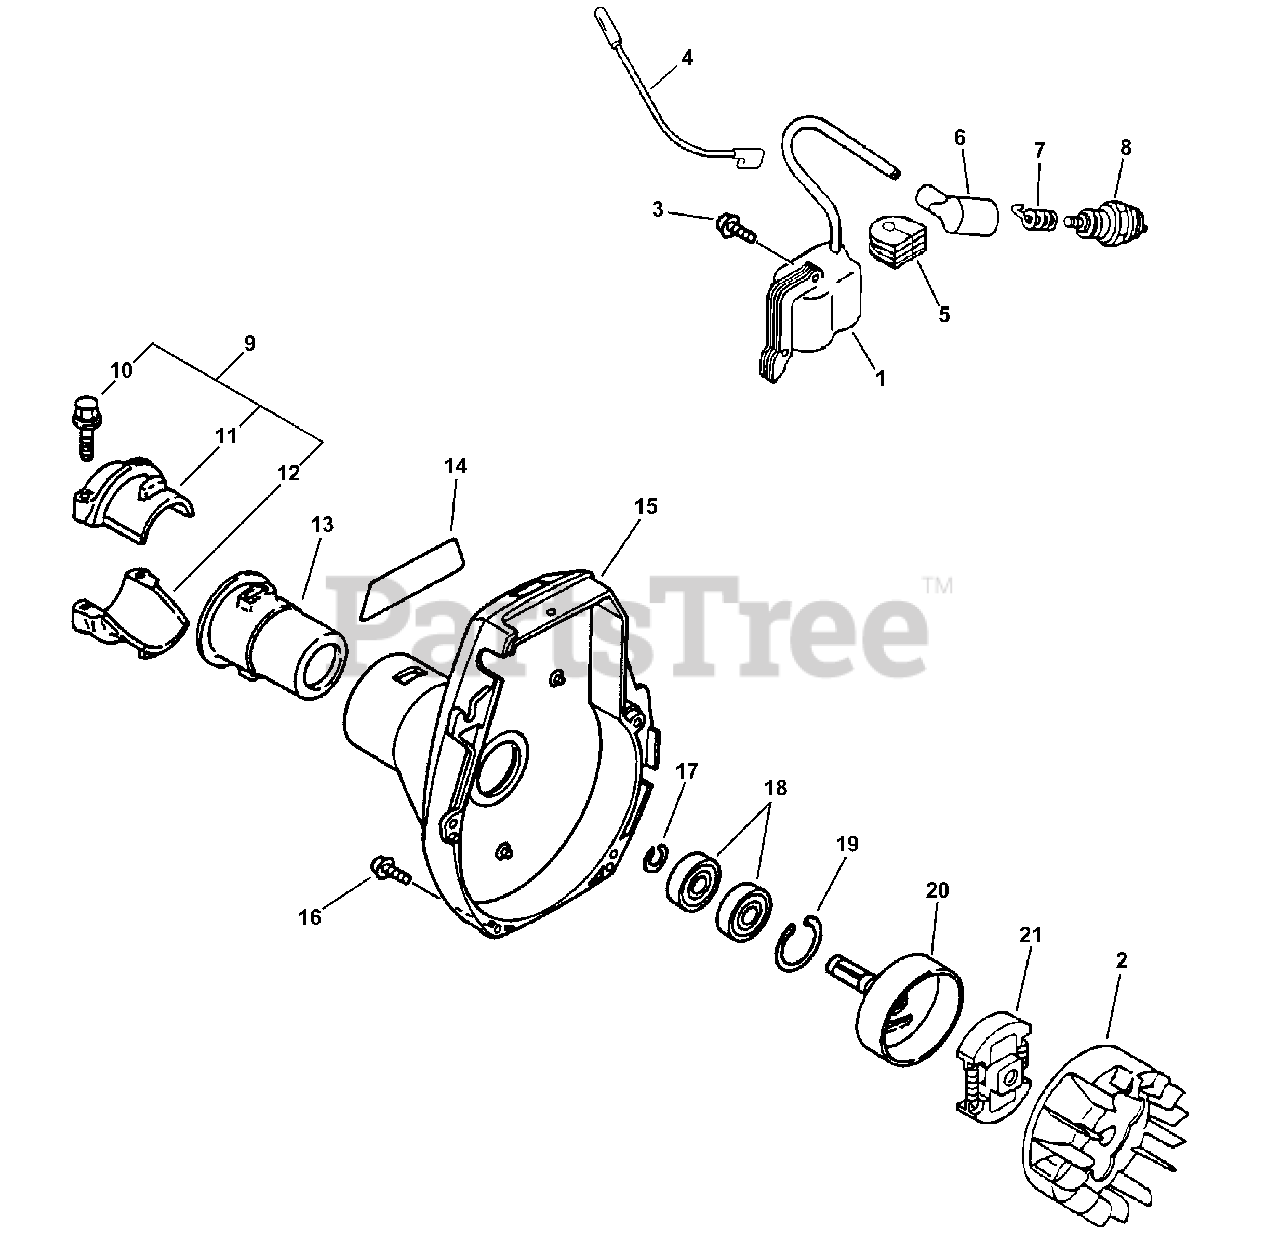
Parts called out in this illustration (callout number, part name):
1	COIL, IGNITION
2	FLYWHEEL
3	SCREW 4×22
4	LEAD
6	CAP, SPARK PLUG
7	TERMINAL, SPARK PLUG
8	SPARK PLUG - BPM7A
9	RETAINER KIT
10	BOLT - 5×25
11	HOLDER, MAIN PIPE - UPPER
12	HOLDER - LOWER
13	CUSHION Ø25
14	LABEL - MODEL SRM-2100
14	LABEL - MODEL SRM-2110
15	COVER ASSY, FAN
16	BOLT 4×16
17	RING, RETAINING - 12
18	BEARING, BALL 6001
19	RING, SNAP 28
20	DRUM, CLUTCH
21	CLUTCH ASSY
